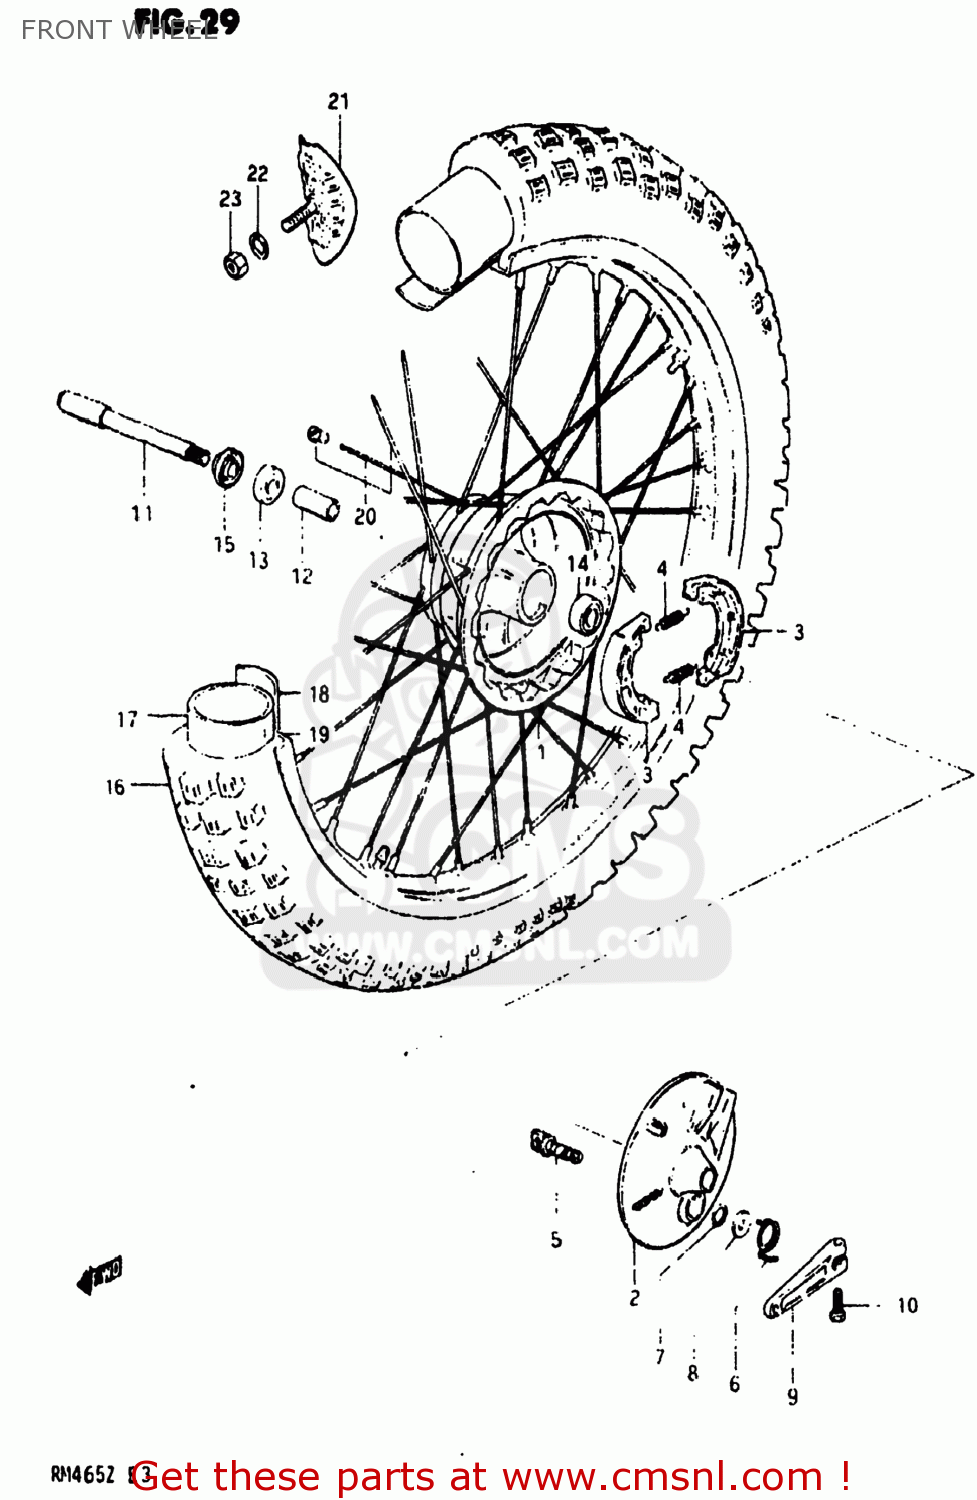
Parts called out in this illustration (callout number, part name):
1	HUB,FRONT
2	PANEL,FRONT HUB
3	SHOE,BRAKE
4	SPRING
5	CAM,FRONT BRAKE
6	SPRING
7	O RING(D:2.5,ID:11.4)
8	WASHER(12.5X20X1)
9	LEVER,FRONT BRAKE CAM
10	BOLT
11	AXLE,FRONT
12	SPACER,FRONT HUB BEARING
13	BEARING
14	BEARING
15	SPACER,FRONT AXLE,RIGHT
16	TIRE,FRONT
17	TUBE,INNER
18	PROTECTOR,WHEEL,INNER
19	RIM,FRONT WHEEL
20	SPOKE SET,FRONT
21	STOPPER,BEAD
22	WASHER
23	NUT
